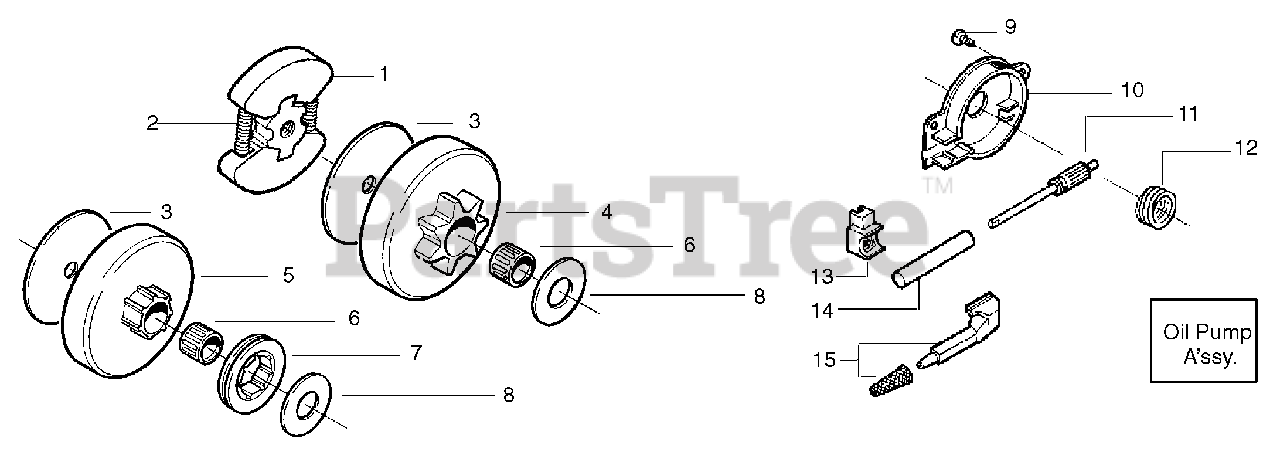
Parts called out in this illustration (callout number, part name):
1	Clutch Assembly
2	Spring - Clutch
3	Clutch Washer
4	Clutch Drum w/Bearing Ass'y. (3/8x6 spur)
4	Clutch Drum w/Bearing Ass'y. (.325 )
5	Drum, Adapt. & Bearing Kit
6	Clutch Bearing
7	Rim-Floating (.325)
8	Thrust Washer
10	Oil Pump Housing
11	Plunger & Gear Assembly
12	Oil Pump Worm
13	Oil Seal
14	Oil Pump Barrel
15	Oil Pick-Up and Screen Assembly
